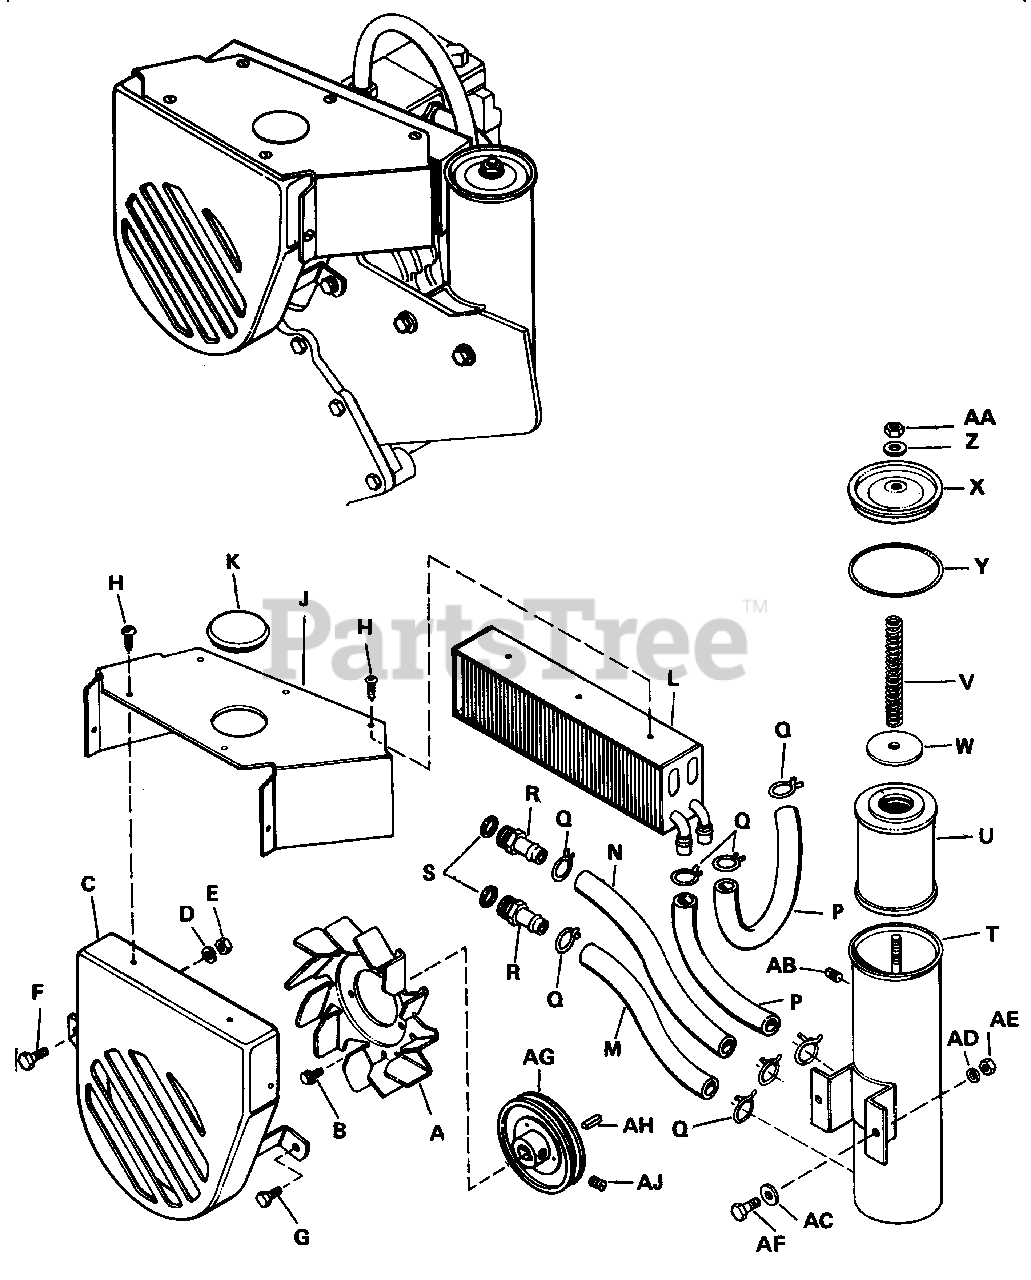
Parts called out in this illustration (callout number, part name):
B	Hex. Screw, Washer Hd.
C	Fan Shroud Assembly
D	Lock Washer, 5/16"
E	Full Hex. Nut
F	Hex. Capscrew
G	Hex. Screw, Thd.
H	Tapscrew, Round hd. slot
J	Cooler Deflector
L	Oil Cooler
M	Hydraulic Hose
N	Hydraulic Hose
P	Hydraulic Hose
Q	Hose Clamp
R	Beaded Insert
T	Reservoir Assembly
U	Filter Element
X	Reservoir Cover
Z	Nylon Wasner
AA	Elastic Stop Nut
AB	Pipe Plug
AC	Plain Washer, 5/16"
AD	Lock Washer, 5/16"
AE	Full Hex. Nut, 5/16-18"
AF	Hex. Capscrew, 5/16-18 x 3/4"
AG	Driven Pulley
AJ	Cup Pt. Socket Hd. Set Screw, 5/16-18 x 5/16"
